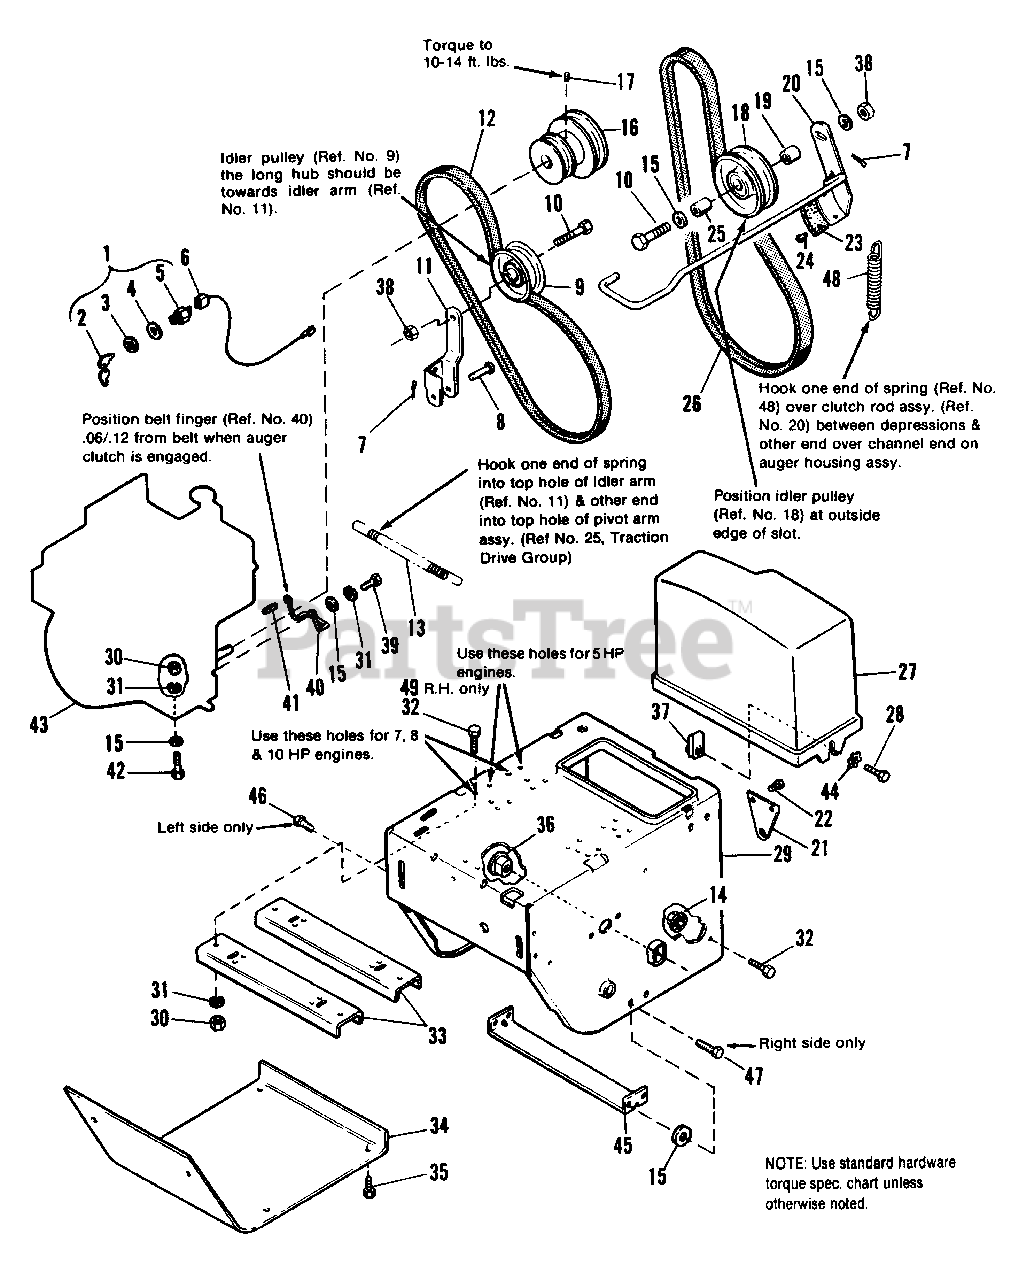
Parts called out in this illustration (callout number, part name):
1	SWITCH, Key (Incl. Ref. Nos. 2, 3, 4 & 5)
3	NUT, Hex, 5/8-32
4	LOCKWASHER, Int. 5/8
6	WIRE, Ground
7	PIN, Cotter, 1/8 x 3/4
8	PIN
9	PULLEY, Idler
10	CAPSCREW, Hex Hd., 3/8-16 x 1-1/2
11	ARM, Idler, Traction
12	** BELT, Traction
12	* BELT, Traction
13	** SPRING, Idler
13	* SPRING, Idler
14	NUT, Hex, Whizlock, 5/16-18
15	WASHER, Flat, 5/16
16	PULLEY, Engine
17	SETSCREW, Socket Hd., 5/16-18 x 5/16
18	PULLEY ASSY.
20	CLUTCH ROD ASSY. (Incl. Ref. Nos. 23 & 24)
21	BRACKET, Clutch Pivot
22	SCREW, Taptite, 1/4-20 x 1/2
26	BELT, Auger Drive
27	GUARD, Belt
28	SCREW, Truss Hd., 5/16-18 x 3/4
29	* FRAME, Main (Later Models - see below)
29	** FRAME, Main (Early Models - see below)
30	NUT, Hex, 5/16-18
31	LOCKWASHER, 5/16
32	CAPSCREW, Whizlock, 5/16-18 x 3/4 (Qty. 8 on 1690543 & 1690775)
33	BRACKET, Engine Mounting
34	COVER, Bottom
35	SCREW, Taptite, 1/4-20 x 3/8
36	BUSHING, Axle
37	NUT, Pal, 5/16-18
38	LOCKNUT, Jam, 3/8-16
39	CAPSCREW, Hex Hd., 5/16-24 x 3/4
40	BELT FINGER
41	KEY, 3/16 x 3/16 x 1-1/2
42	CAPSCREW, Hex Hd., 5/16-18 x 1-3/4
43	ENGINE, Tecumseh, 5 H.P.
43	ENGINE, Tecumseh, 7 H.P.
43	ENGINE, Tecumseh, 8 H.P.
43	ENGINE, Tecumseh, 10 H.P.
44	LOCKWASHER, Ext. Tooth, 5/16
45	SUPPORT, Tie Bar
46	SCREW, Taptite, 5/16-18 x 3/8 (left side only)
47	SCREW, Taptite, 5/16-18 x 3/4 (right side only)
48	SPRING, Brake
49	CAPSCREW, Hex Hd., 5/16-18 x 3/4
